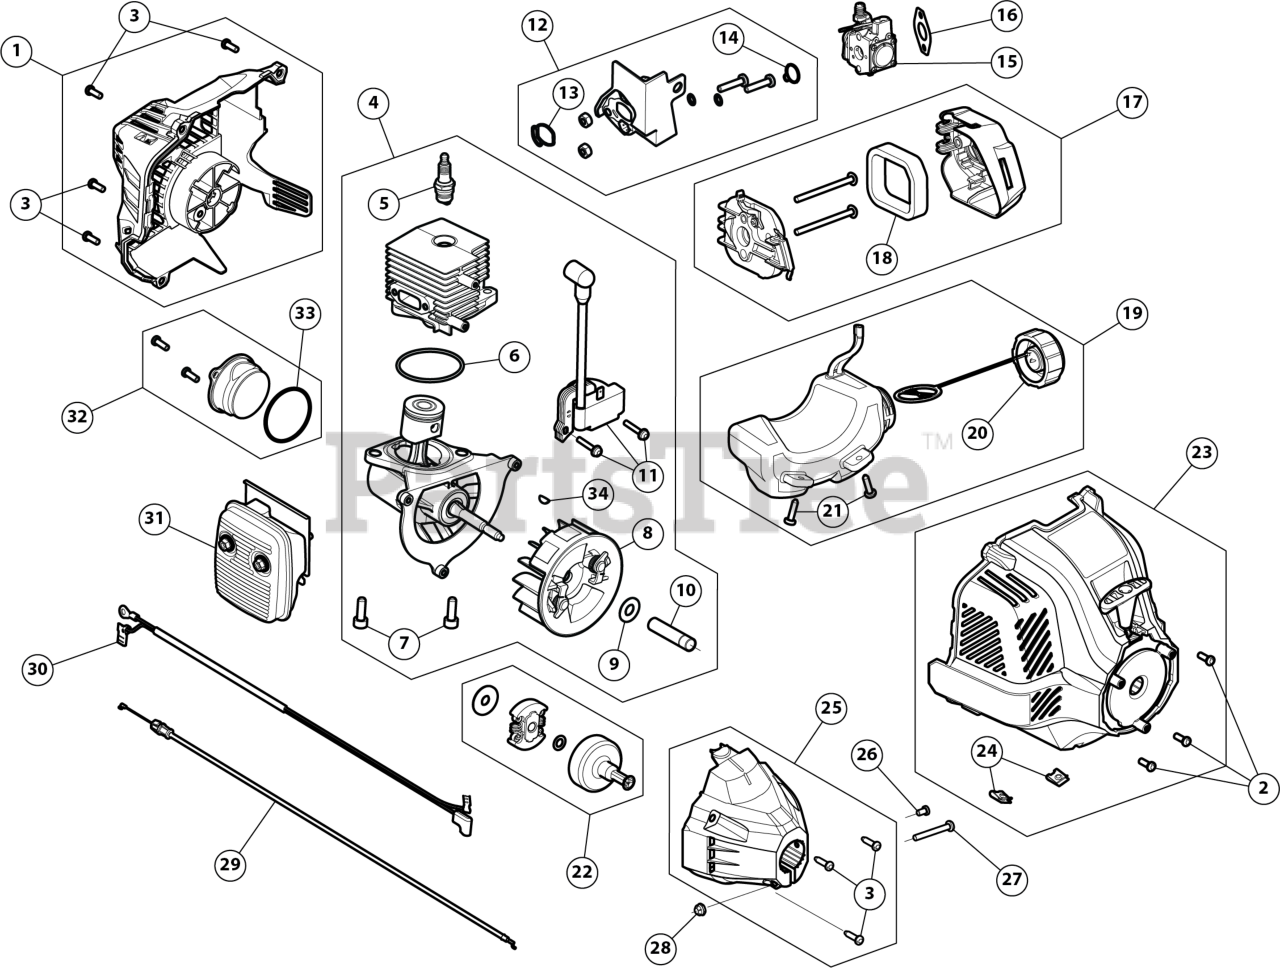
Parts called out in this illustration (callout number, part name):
1	REAR ENGINE COVER
2	SCREW #10-24X11/16 T-25
3	SCREW 8-16 x 3/4
4	SHORT BLOCK 25cc
5	SPARK PLUG
6	O-RING SEAL CYLINDER
7	SCREW 5/16-18x3/4 T40
8	FLYWHEEL ASSEMBLY
9	BELL WASHER
10	SPACER :2.165"
12	INTAKE ASSEMBLY
13	INSL/CYL SEAL
14	CARBURETOR SEAL
15	CARBURETOR
16	GASKET CARB
17	AIR CLEANER COVER
18	AIR FLITER
19	FUEL TANK ASSEMBLY
20	FUEL CAP ASSEMBLY
21	SCREW:10-6 x .75
22	SMALL CLUTCH ASSEMBLY W/SMALL DRUM
23	STARTER HOUSING
24	NUT, TINNERMAN U-T
25	CLUTCH COVER
26	SCREW, 8-32 x .312 P
27	SCREW 10-24 X 1.12
29	THROTTLE CABLE
30	LEAD WIRES
32	CRANKCASE COVER
33	O-RING SEAL CRANKCASE
34	WOODRUFF KEY #403-.125 x .375
